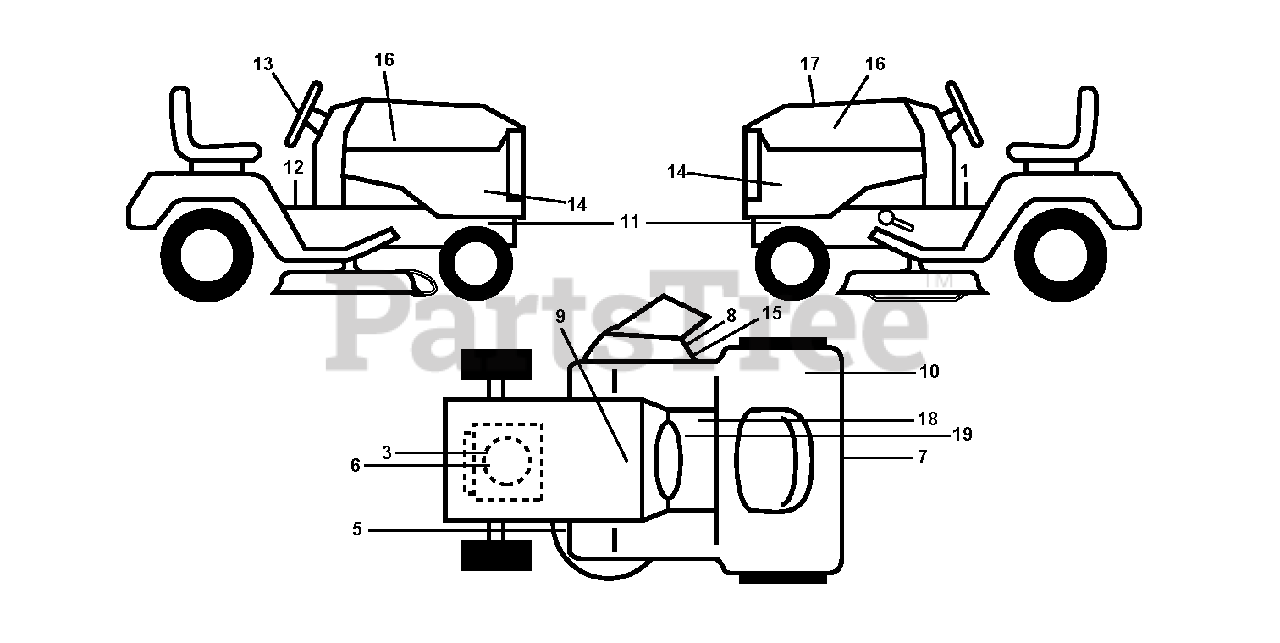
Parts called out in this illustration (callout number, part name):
5	DECAL.MOWER.SCH.48/54
8	DECAL.INTERNATIONL.CUTFINGER
9	DECAL BTRY SYMBOLS
10	DECAL.FENDER
15	DECAL, DEFLECT WARNING
19	DECAL PARK BRAKE
